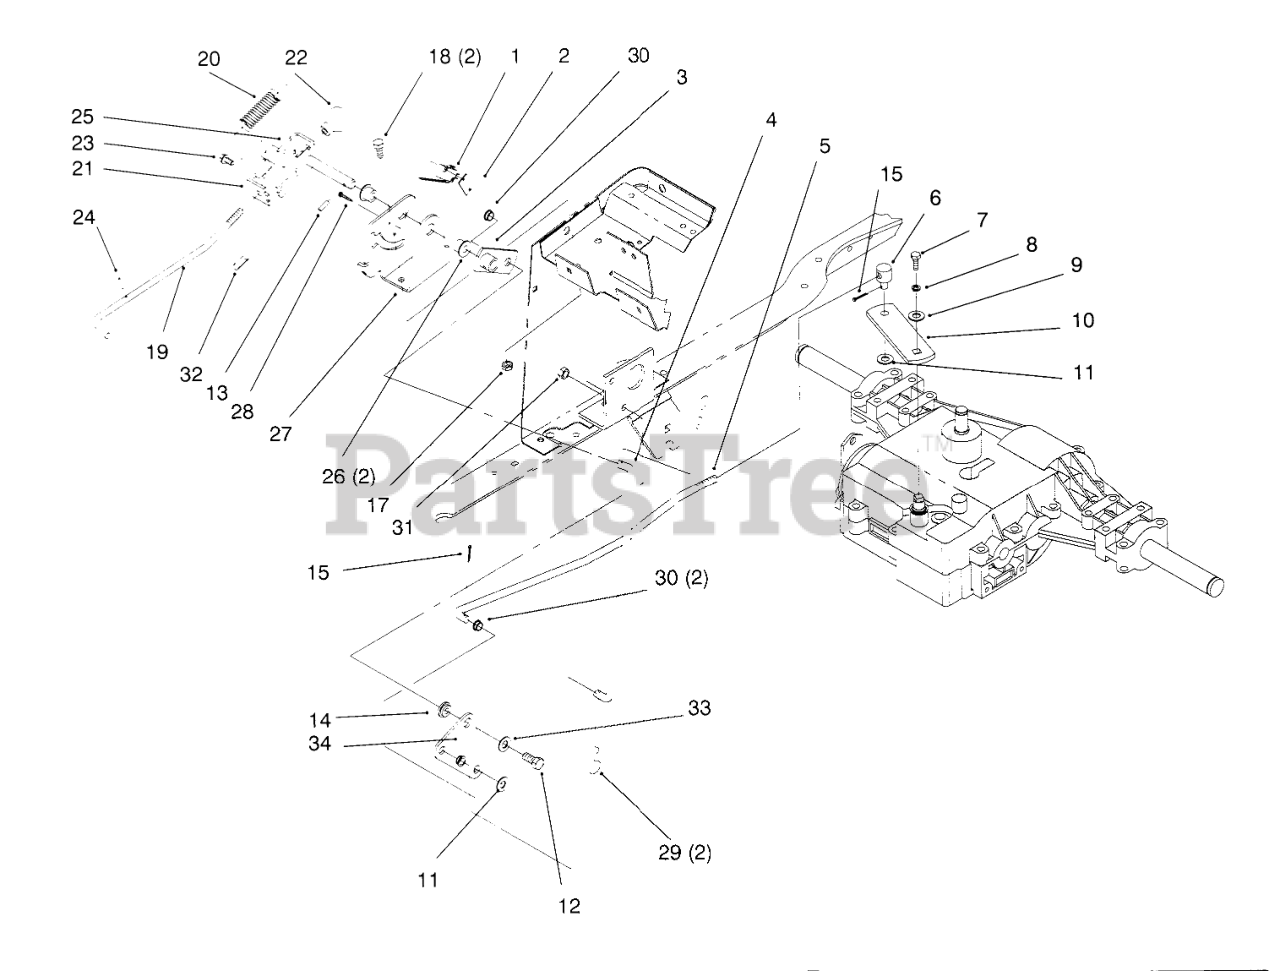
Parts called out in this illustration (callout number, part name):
1	Switch-Clutch (Only On: 72042,72062)
2	Nut-Speed (Only On: 72042,72062)
3	Tube-Linkage (Only On: 72042,72062)
4	Rod (Only On: 72042,72062)
5	Rod-Shift Transaxle (Only On: 72042,72062)
6	Trunnion (Only On: 72042,72062)
7	Screw (Only On: 72042,72062)
8	Washer-Lock (Only On: 72042,72062)
9	Spacer-Transmission (Only On: 72042,72062)
10	Arm-Shift (Only On: 72042,72062)
11	Washer-Flat (Only On: 72042,72062)
12	Screw-H H (Only On: 72042,72062)
13	Pin-Roll (Only On: 72042,72062)
14	Bushing (Only On: 72042,72062)
15	Pin-Cotter (Only On: 72042,72062)
17	Nut-Lock (Only On: 72042,72062)
18	Screw-HH (Only On: 72042,72062)
19	Rod-Shift (Only On: 72042,72062)
20	Spring-Compression (Only On: 72042,72062)
21	Bracket-Shaft (Only On: 72042,72062)
22	Knob (Only On: 72042,72062)
23	Screw-TAP (Only On: 72042,72062)
24	Pin-Roll (Only On: 72042,72062)
25	Pivot-Shift (Only On: 72042,72062)
26	Bushing (Only On: 72042,72062)
27	Bracket-Pivot Mount (Only On: 72042,72062)
28	Screw (Only On: 72042,72062)
29	Pin-Cotter (Only On: 72042,72062)
30	Bearing-Shift Link (Only On: 72042,72062)
31	Nut-Lock (Only On: 72042,72062)
32	Decal-Reverse Shift (Only On: 72042)
32	Decal-Reverse Shift (Only On: 72062)
33	Washer-Flat (Only On: 72042,72062)
34	Bracket-Pivot (Only On: 72042,72062)
